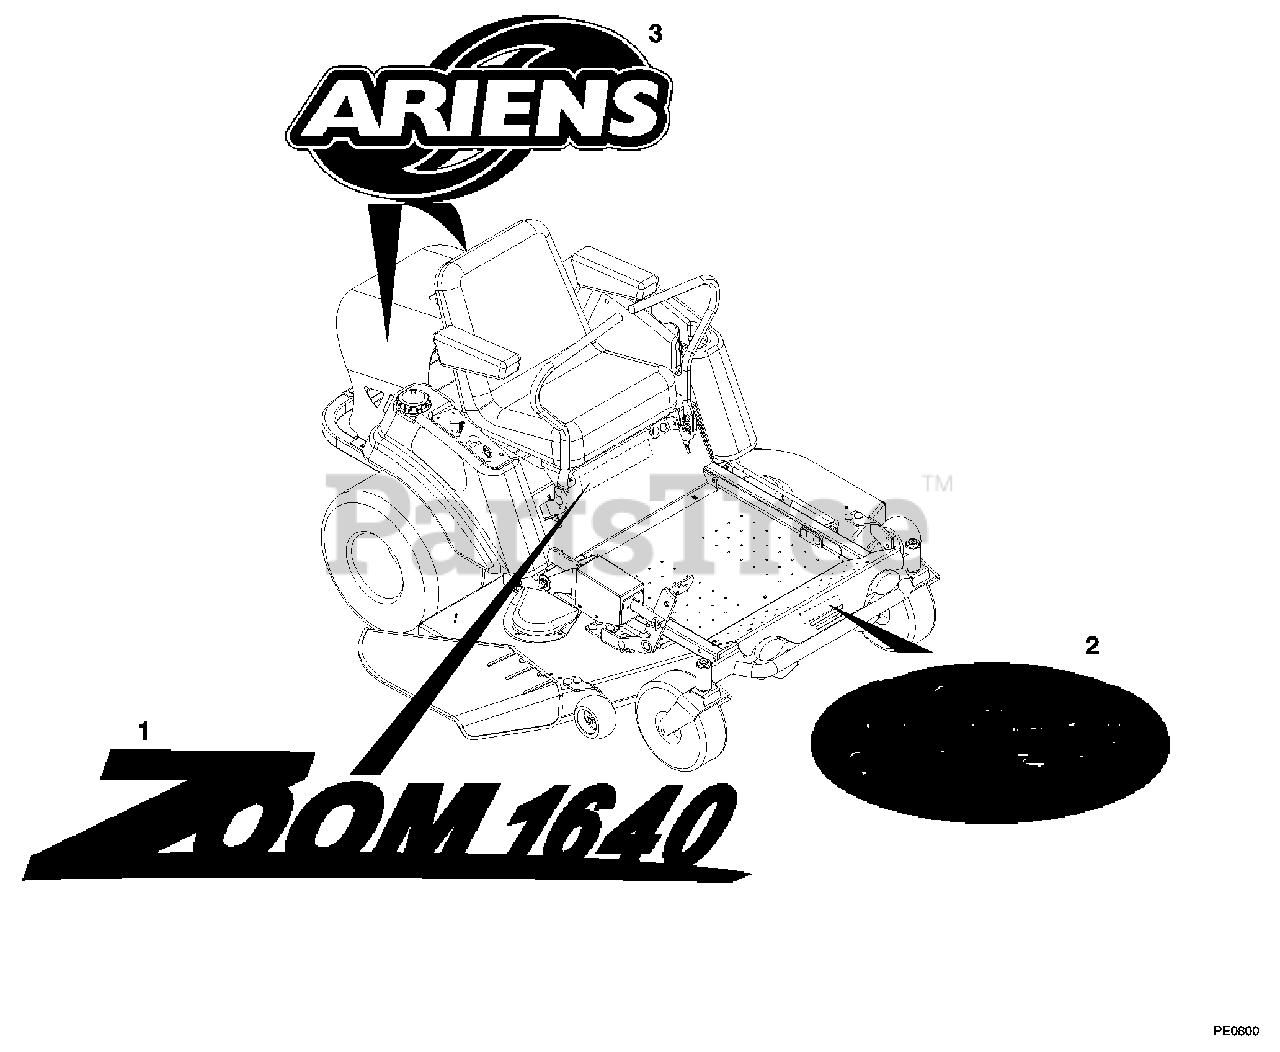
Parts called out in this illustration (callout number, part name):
1	DECAL ZOOM 1640
2	DECAL-ARIENS JEWEL
3	DECAL ZOOM HOOD
